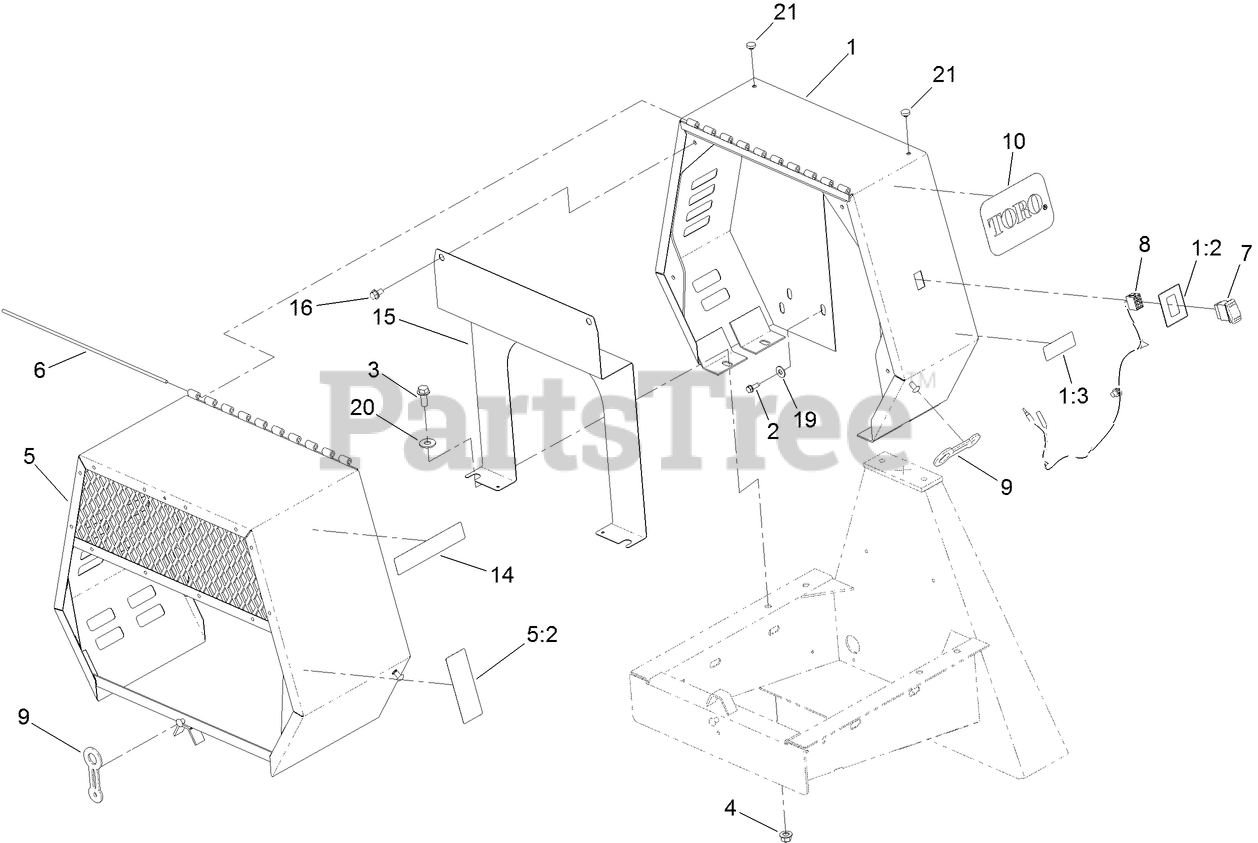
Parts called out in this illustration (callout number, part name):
1	STATIONARY COWL ASM
1:2	DECAL-STOP, ENGINE
1:3	DECAL-ARRESTER, SPARK
2	SCREW-THD ROLL, HWH
3	SCREW-HHF
4	NUT-LOCK
5	MOVABLE COWL ASM
5:2	DECAL-WARNING
7	SWITCH
8	HARNESS-WIRE, MIXER
9	LATCH-RUBBER
10	DECAL
15	PLATE-ENGINE
16	SCREW-HWH
19	WASHER-FLAT
20	WASHER-FLAT
21	BUMPER
